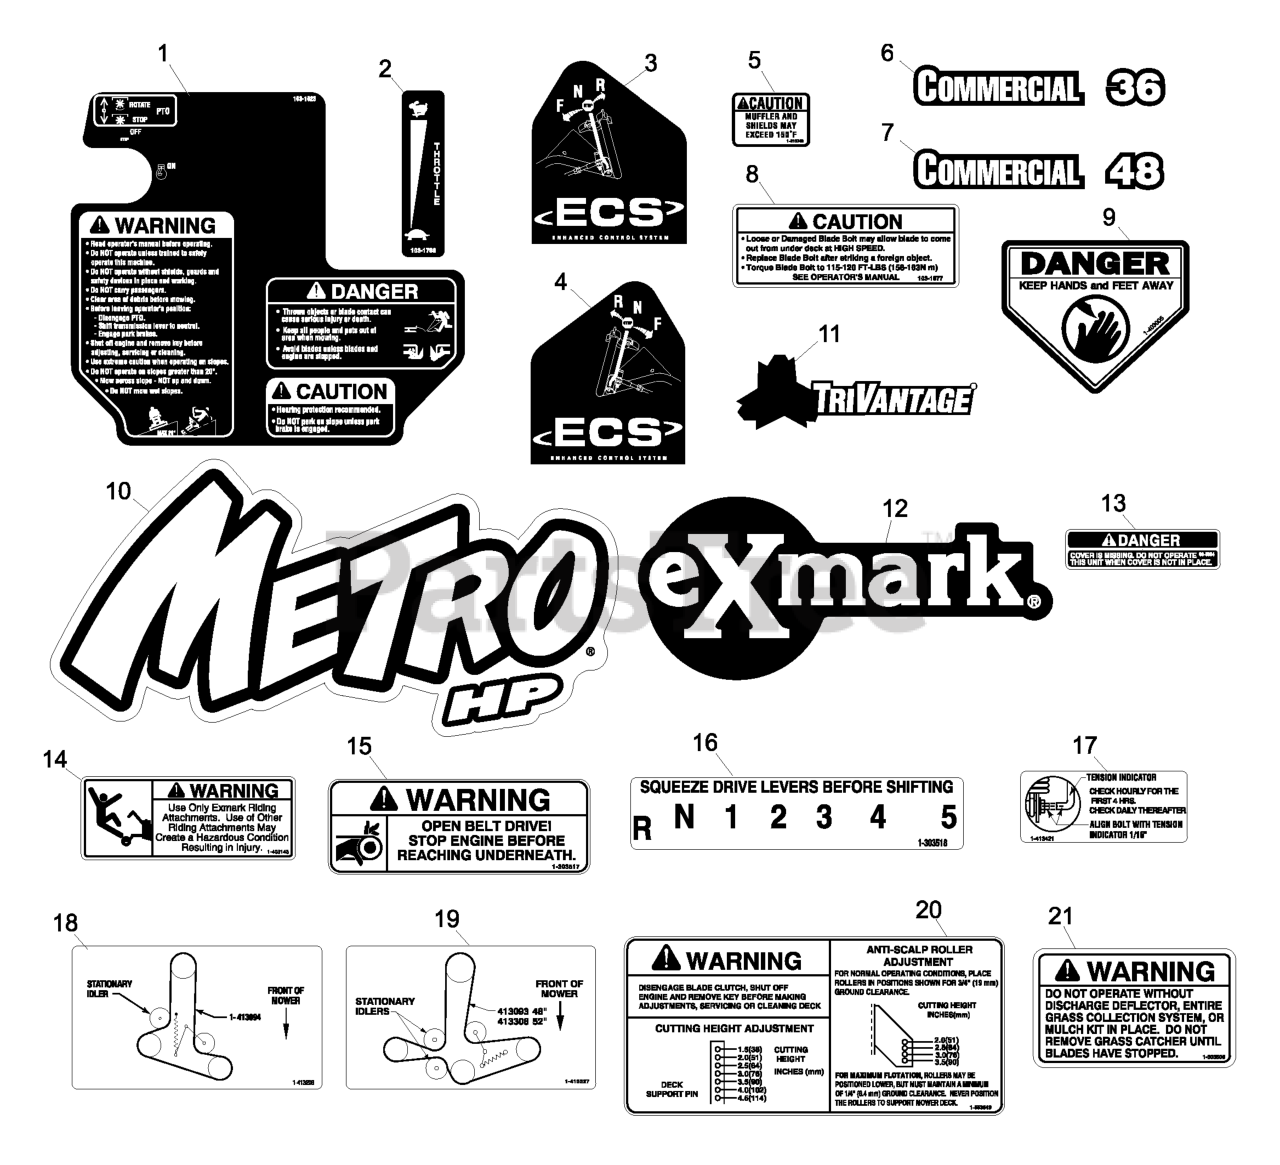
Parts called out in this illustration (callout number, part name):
1	DECAL,METRO ECS CONSOLE
2	DECAL,THROTTLE ONLY
3	DECAL,LH ECS INSTRUCTION
4	DECAL,RH ECS INSTRUCTION
6	DECAL,COMMERCIAL 36
7	DECAL,COMMERCIAL 48
8	DECAL,BOLT TORQUE
9	DECAL-DANGER
12	DECAL,EXMARK LOGO
13	DECAL-COVER, MISSING
14	DECAL,SULKY WARNING
15	DECAL,BELT DRIVE
16	DECAL,SHIFTER
17	DECAL,INDICATOR
18	DECAL,BELT ROUTING
19	DECAL,BELT ROUTING
20	DECAL,ANTI SCALP
21	DECAL-WARNING, DISCHARGE
